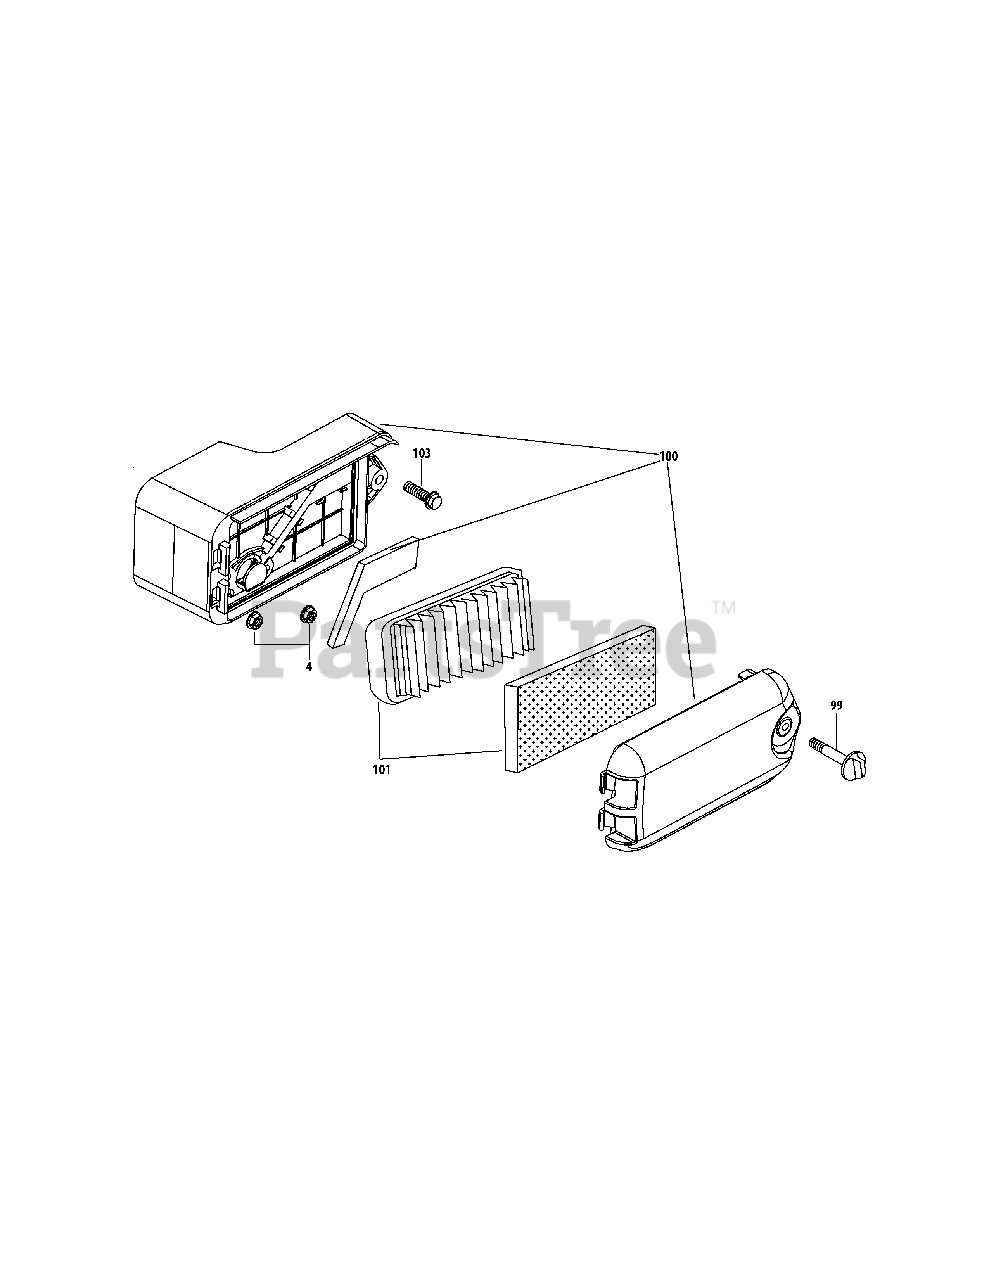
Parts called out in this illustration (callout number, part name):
4	Nut M6 X 10 Mm
99	Air Cleaner Cover Thumb Screw
100	Air Filter Housing Asm
101	Air Filter Kit
103	Blot M6×30
